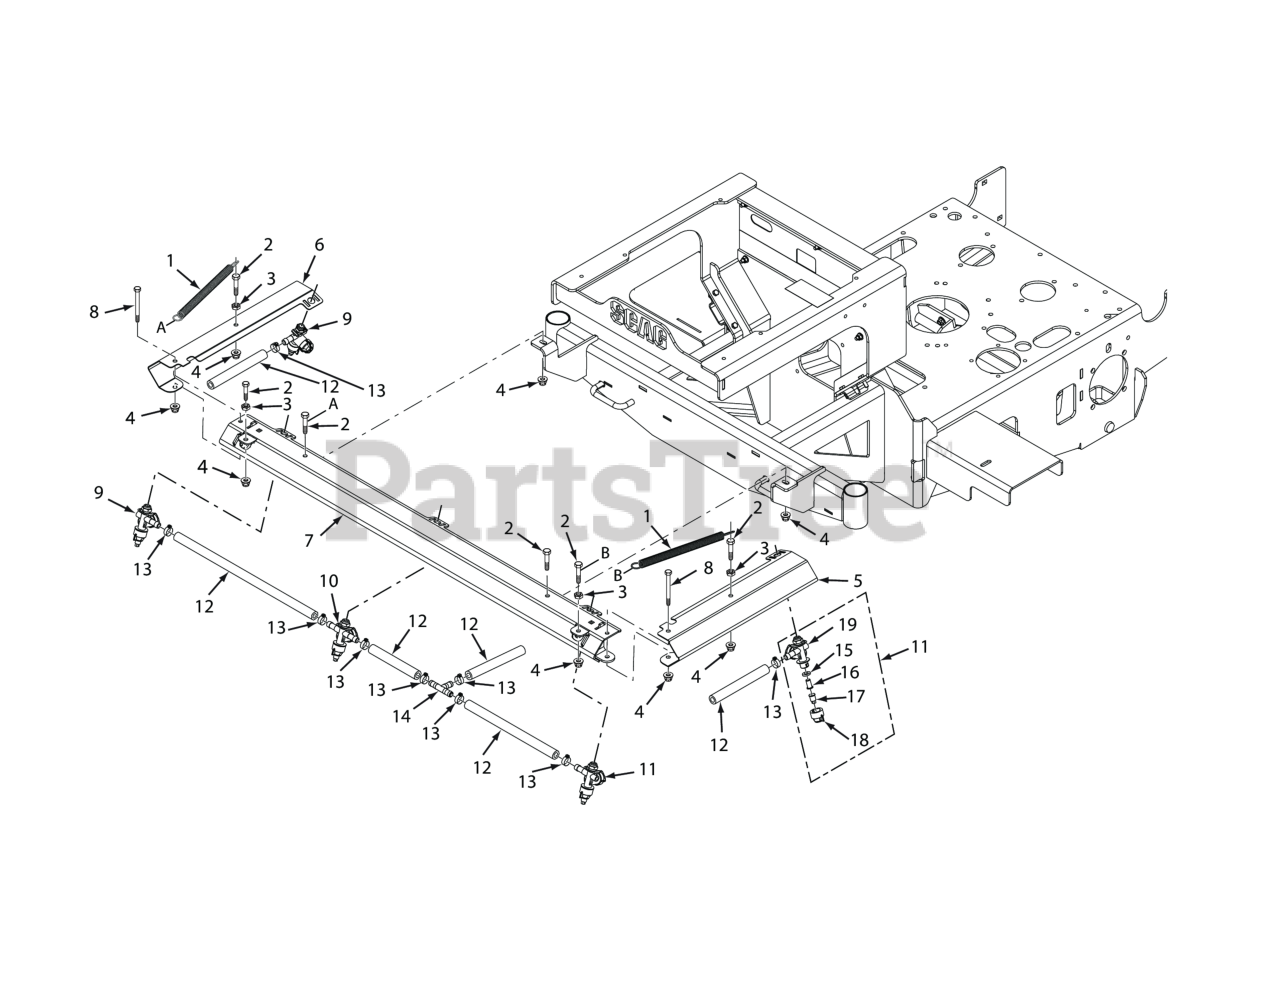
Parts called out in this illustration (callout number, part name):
1	Spring, Boom Arm
2	Bolt, Hex Head 3/8 - 16 x 1.50 - Stainless Steel
3	Nut, 3/8 - 16 - Stainless Steel
4	Nut, Flange Elastic Stop 3/8 - 16 - Stainless Steel
5	Boom, LH
6	Boom, RH
7	Boom, Main
8	Bolt, Hex Head 3/8- 16 x 3.50 - Stainless Steel
9	Nozzle Assembly, RH
10	Nozzle Assembly, Main
11	Nozzle Assembly, LH
12	Hose, 1/2" EPDM (order by the inch)
13	Clamp, Cable 3/4" I.D.
14	Fitting, Tee 1/2" Hose Barb
15	Washer, Rubber
16	Nozzle, Strainer #50 Mesh
17	Nozzle Tip
18	Nozzle Cap
19	Nozzle Body, Single LH (used in #11)
